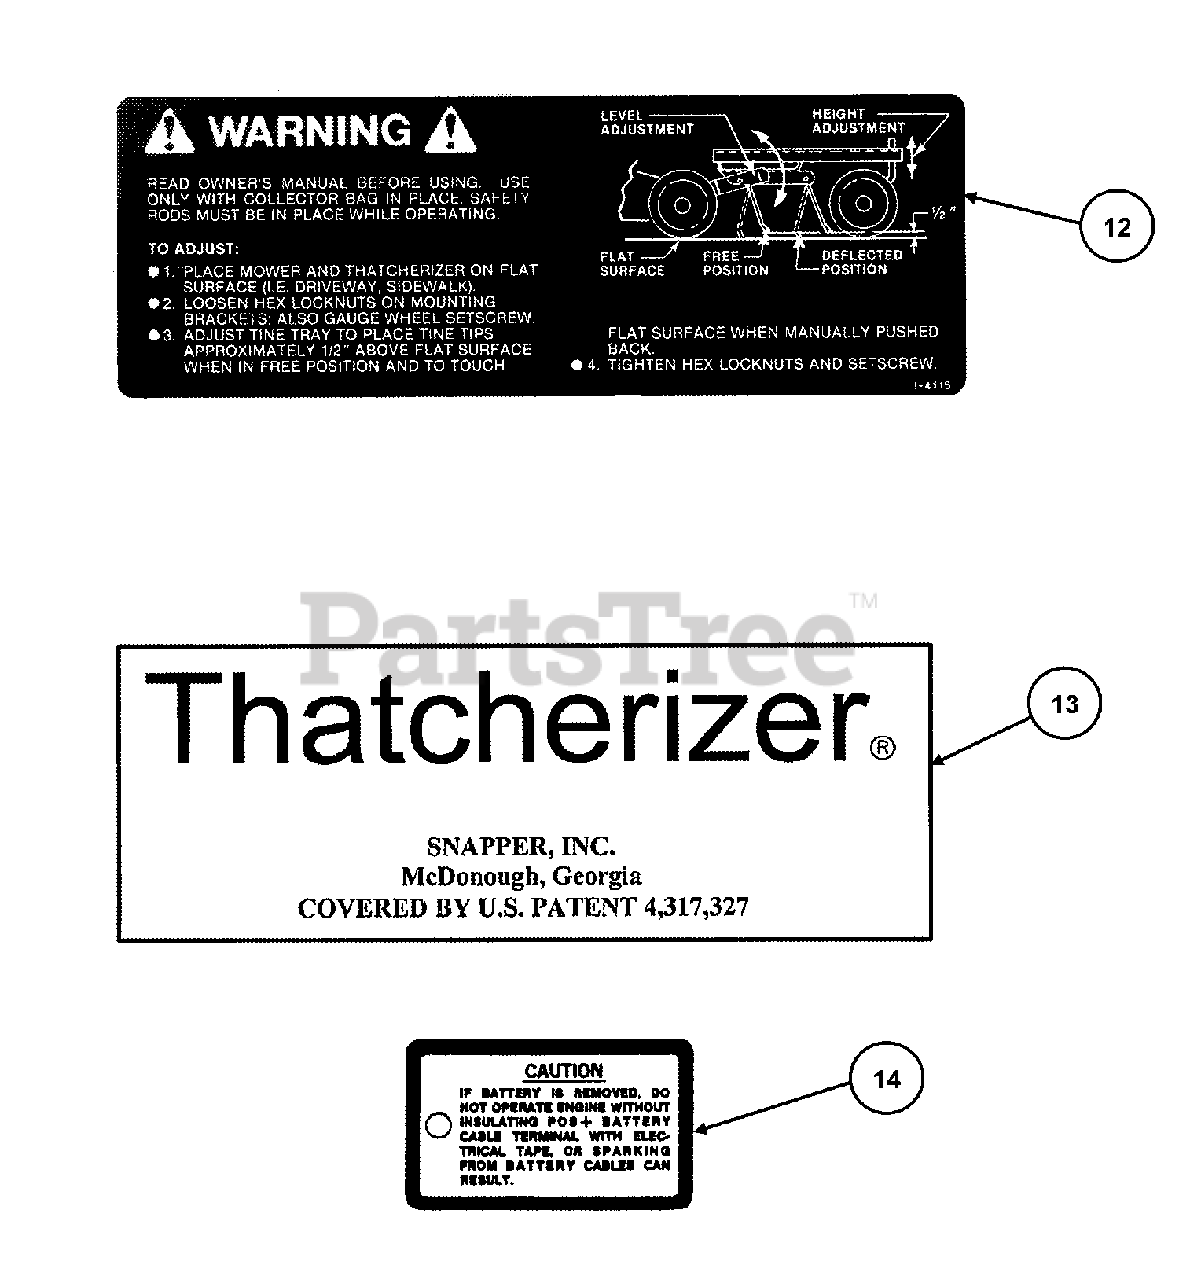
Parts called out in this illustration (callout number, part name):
12	DECAL, Warning Thatcherizer
13	DECAL, Thatcherizer
14	DECAL, Caution Tag
